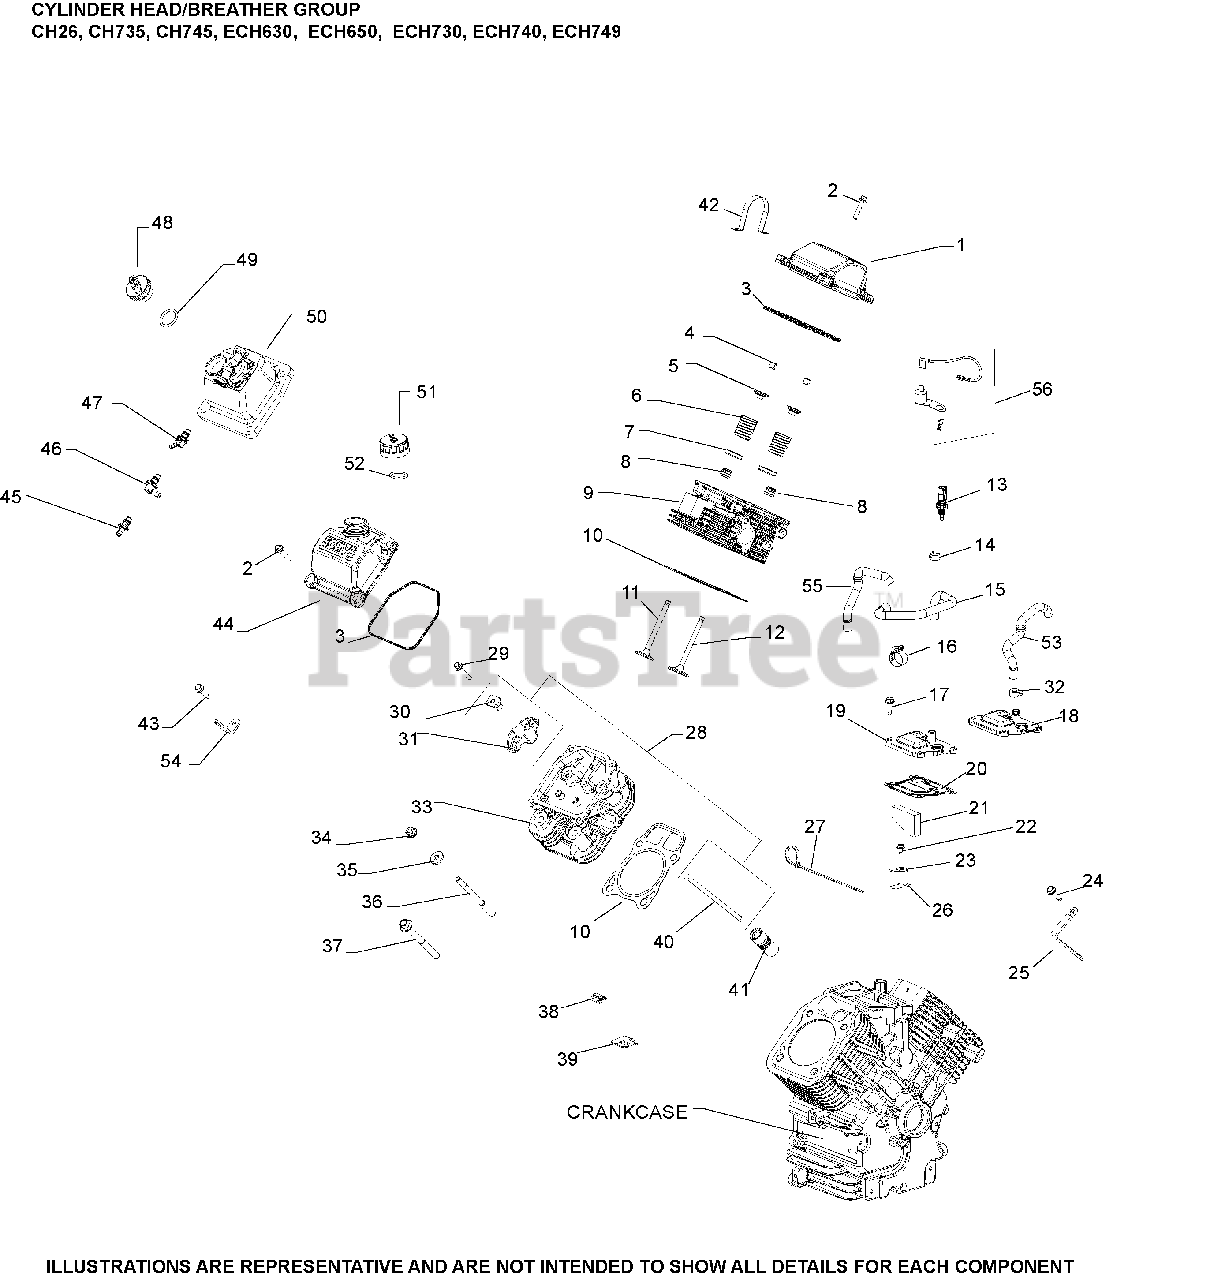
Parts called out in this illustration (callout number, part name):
1	KIT, VALVE COVER-PLAIN
2	SCREW, FLG M6X1.0X30
3	O-RING (YELLOW), VALVE COVER
4	KIT, RETAINER
5	CAP, VALVE SPRING
6	SPRING, VALVE
7	RETAINER, SPRING
8	SEAL, VALVE BAND
9	KIT, CYLINDER HEAD #1
10	KIT, GSKT CYL HD (C22-23 674CC)
11	VALVE, EXHAUST
11	VALVE, EXHAUST (.25)
12	VALVE, INTAKE (STD)
12	VALVE, INTAKE (.25)
13	SENSOR, TEMPERATURE
16	CLAMP, HOSE-USE 25 237 32-S
17	SCREW, THREAD FORMING
19	COVER, BREATHER
20	GASKET, BREATHER
21	FILTER, BREATHER
22	SCREW, FLG THD FRM M5X.8X10
23	RETAINER, REED
25	STRAP, LIFT
26	REED, BREATHER
28	KIT, VALVE TRAIN
29	SCREW, FLG M6X1.0X34
30	PIVOT, ROCKER ARM
31	ARM, ROCKER
32	CLAMP SPRING HOSE
33	KIT, CYLINDER HEAD #2
37	SCREW, FLG M10X1.5X90
38	CLIP, O2 SENSOR
39	BRACKET, OXYGEN SENSOR
40	ROD, PUSH
41	LIFTER, VALVE HYDRAULIC - (#2535111S)
43	SCREW, THREAD FORMING
45	KIT, STRAIGHT FITTING
46	KIT, 90 DEG. FITTING
48	CAP ASSY, OIL FILL (YELLOW)
50	KIT, VALVE COVER-FUEL PUMP
53	BREATHER, HOSE (EFI H/S, LPAC)
54	STRAP, LIFTING
